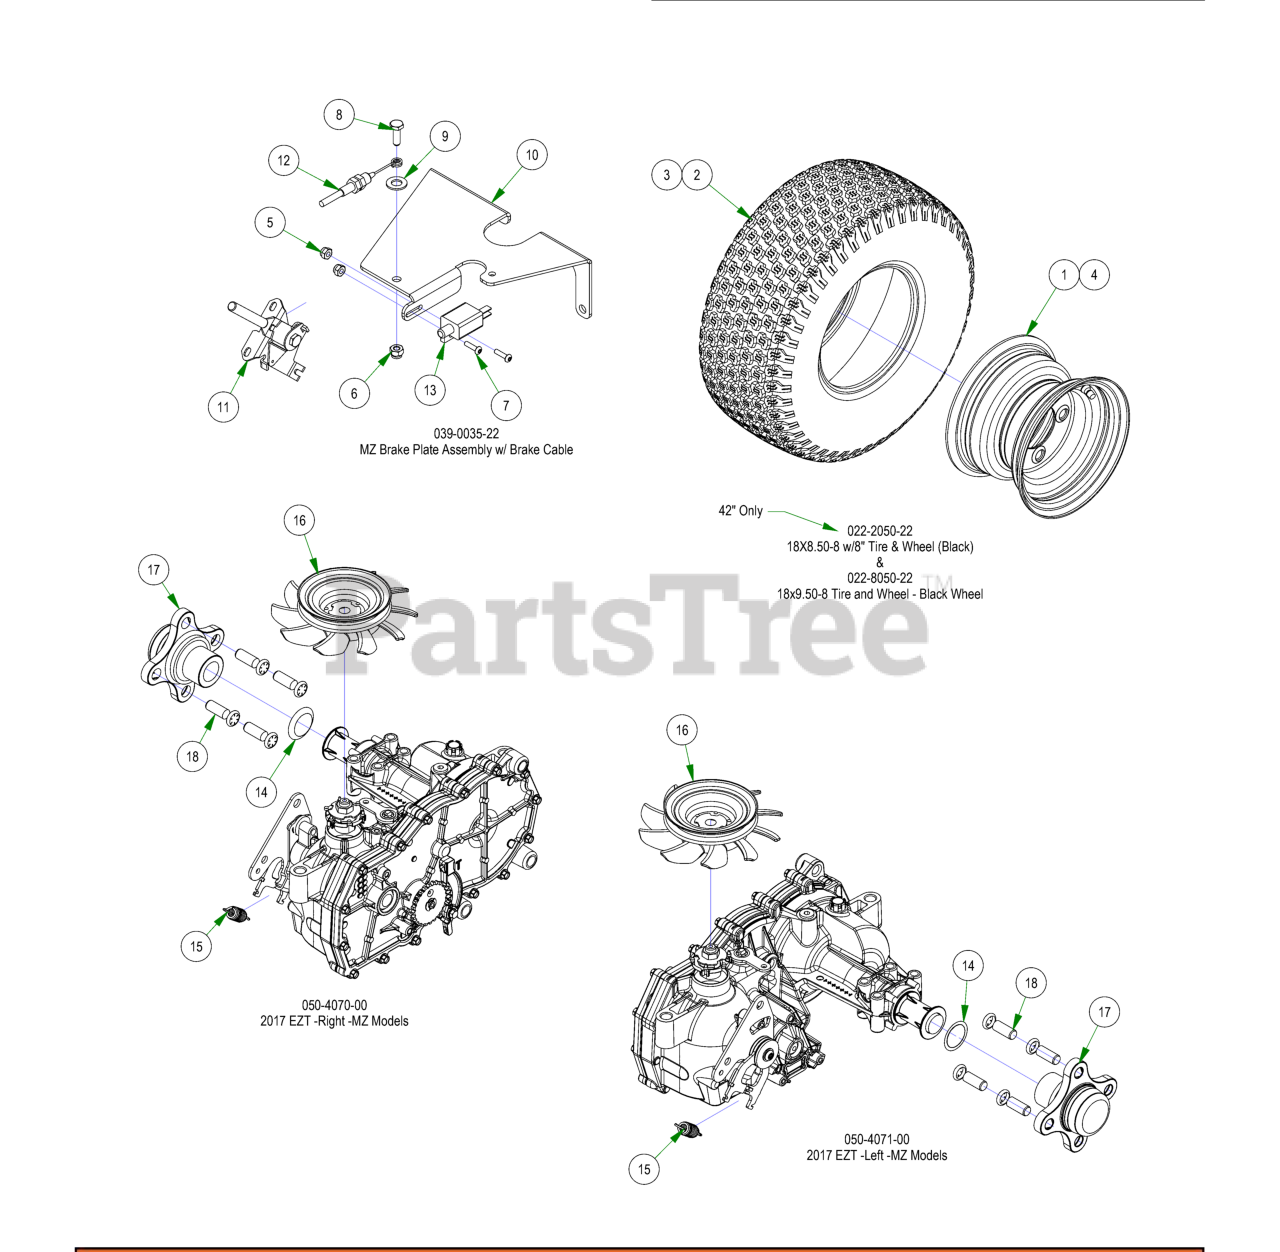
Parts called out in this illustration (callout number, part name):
1	Rim for 022-2050-22
2	Tire for 022-2050-22
3	18x9.50-8 Rear Tire Only 48 MZ
4	Black Rear Wheel 48in MZ
5	#10 Nylock Nut
6	1/4-20 NYLON INSERT LOCKNUT ZINC
7	10-24 X 5/8 BS Button Head Bolt
8	1/4-20 X 3/4 HEX CAP SCREW (GR.5) ZINC
9	.390 ID X .750 OD X .062 THK FLAT WASHER NYLON
10	2017 MZ Brake Lock Bracket
11	Universal Throttle Head - 2012
12	MZ Brake Cable
13	Safety Switch
14	MZ Seal & Retainer Kit
15	Gold Transaxle Spring
16	Fan/Pulley Kit for ZT / 2017 MZ
17	MZ 4 Bolt Hub Kit
18	Transaxle Wheel Studs/ Drum Brake Studs
